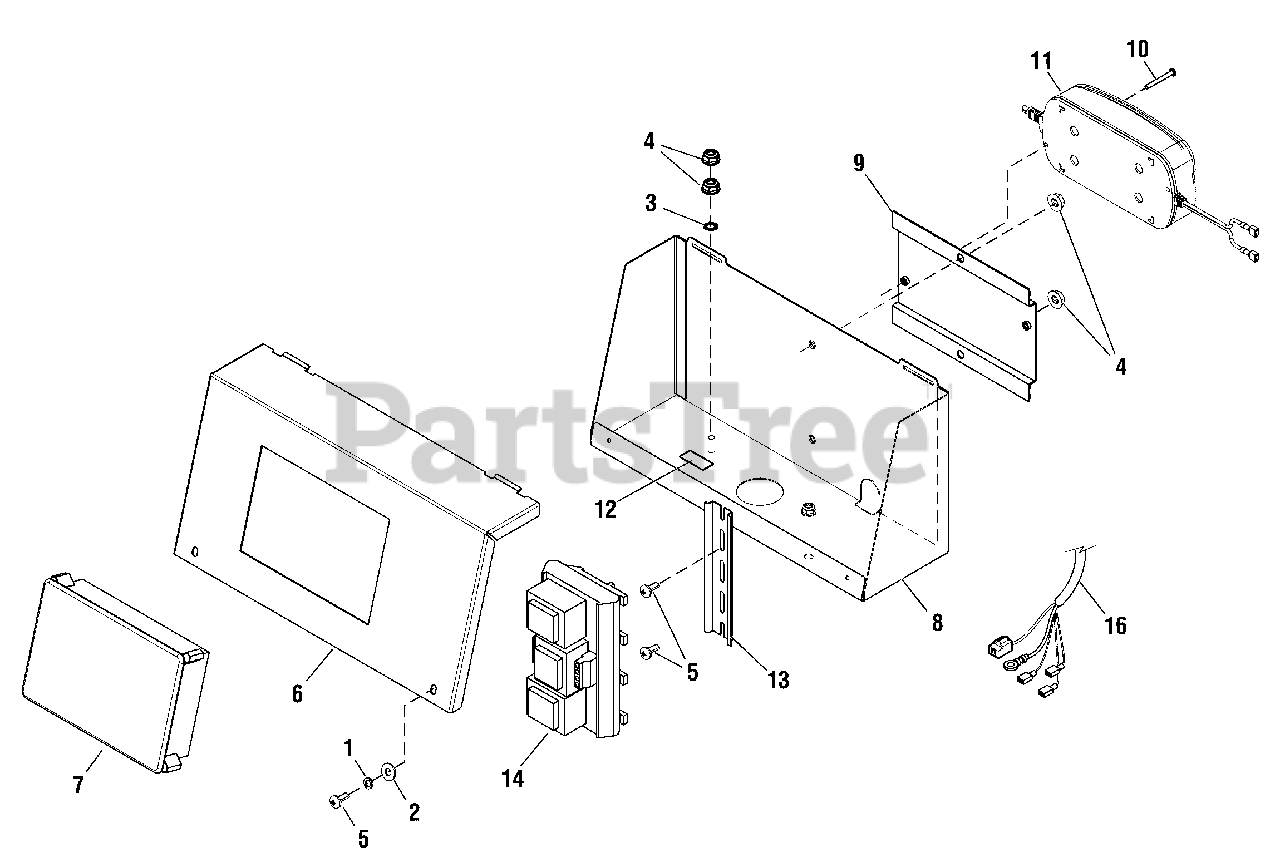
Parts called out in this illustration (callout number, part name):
1	* WASHER, Split Lock, #10
2	* WASHER, Flat, #10
3	* WASHER, External Lock, M6
4	* NUT, Nylock, 1/4-20
5	* SCREW, Phillips Head, Trilobular, #10-32 x 3/4
6	COVER-CONTROL PANEL
8	BOX-CONTROL PANEL
10	* SCREW, Trilobular, #8-32 x 1-1/2
11	CHARGER-BATTERY
12	DECAL
